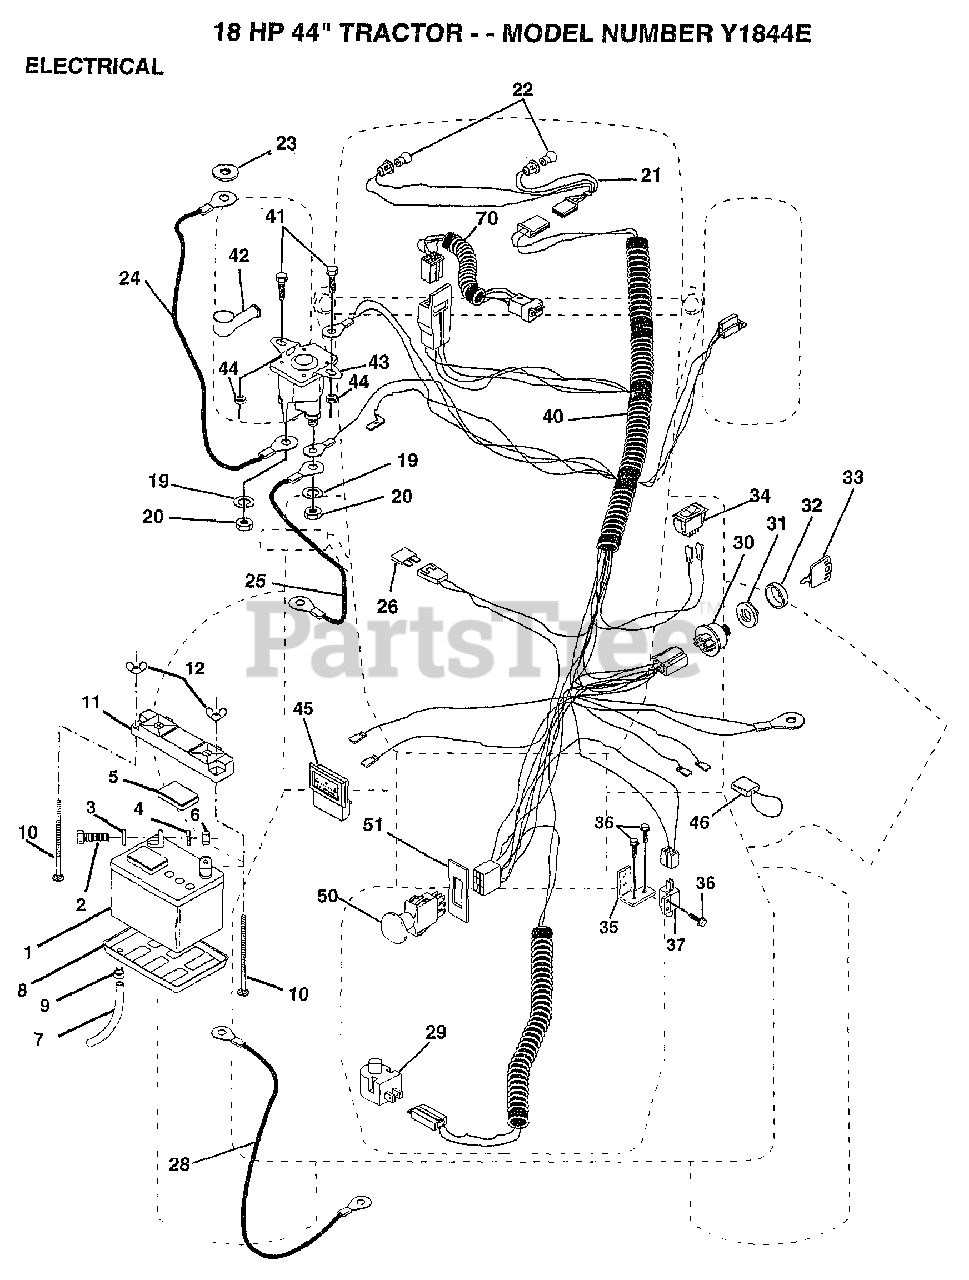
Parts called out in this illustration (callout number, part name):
2	BOLT LT
3	WASHER
4	LOCKWASHER
5	"CAP,BATTERY "
7	"DRAIN TU T, BATT"
8	"TRAY T, BATTERY"
9	HOSE CLAMP T
10	BOLT
20	NUT
21	"HARNESS,LIGHT SOC"
22	HEADLAMP BULB
23	LOCKWASHER
24	"CABLE T, BATTERY"
25	CABLE-BATTERY T
26	FUSE HYT
28	CABLE T
29	SWITCH SEAT
32	COVER KEY SWITCH
33	KEY MLD GEN DELTA
34	SWITCH LT
35	BRACKET LT
36	SCREW
37	SWITCH-INTER. GT
40	HARNESS IGNITION
41	BOLT HXHD FIN
44	NUT HXKEP 1/4X20
45	AMMETER
46	PROTECTION LOOP
51	RING RETAIN PTO
70	HARNESS.ENG.KOHL
